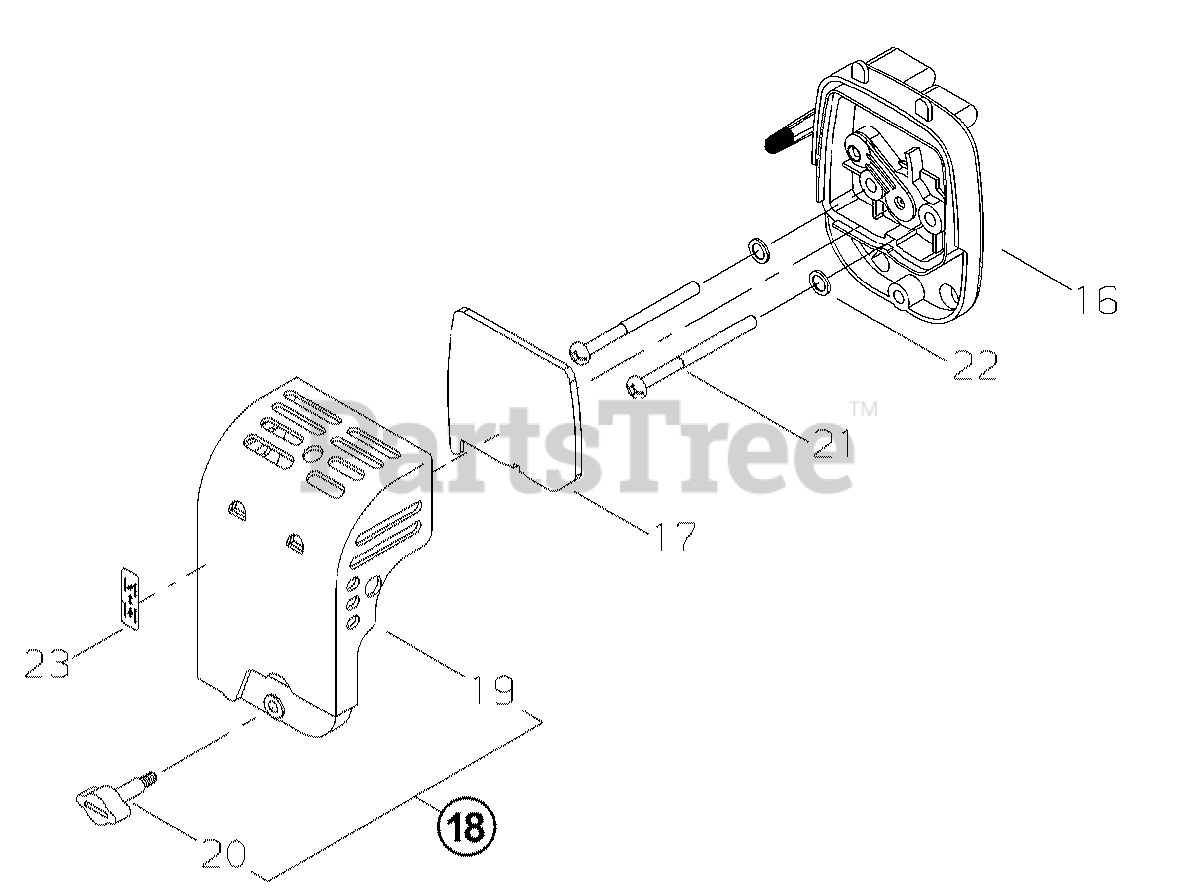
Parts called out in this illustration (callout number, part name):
16	BASE ASSY, AIR FILTER
17	FILTER, AIR
18	COVER ASSY, AIR FILTER
19	COVER, AIR FILTER
20	THUMBSCREW M5
21	SCREW M5×60
22	WASHER 5 MM
23	LABEL, CHOKE
